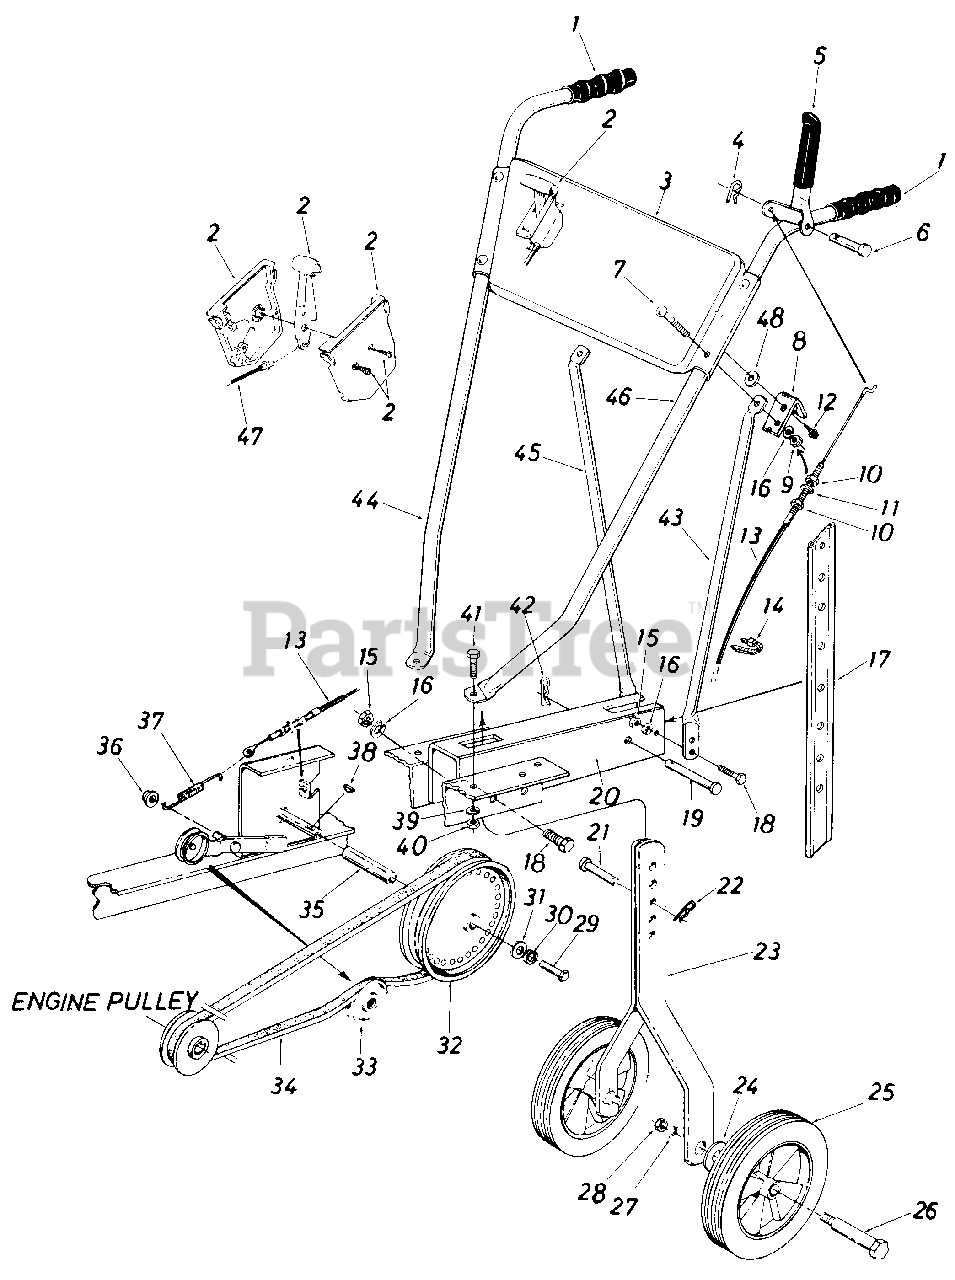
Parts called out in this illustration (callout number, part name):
2	Throttle Control Box
3	Handle Panel
4	Int. Cotter Pin
5	Clutch Grip Ass'y.
6	Clevis Pin
7	Carriage Bolt 5/16-18 x 1.75" Lg.*
8	Cable Support Brkt.
9	Hex Nut 5/16-18 Thd.*
10	Hex Jam Nut 5/16-24 Thd.
11	L-Wash. 5/16" I.D.*
12	Hex Wash Hd. Self-Tap Scr 1/4 20 x 50" Lg.
13	Clutch Control Cable
14	Cable Tie
15	Hex Nut 5/16-18 Thd.*
16	L-Wash. 5/16" I.D.*
17	Depth Bar
18	Hex Bolt 5/16-18 x .75" Lg.*
19	Clevis Pin 1/2" Dia. x 2.50" Lg .
20	Tailpiece Ass'y.
21	Clevis Pin 3/8" Dia. x 2.50" Lg .
22	Hairpin Cotter
23	Wheel Bracket Ass'y.
24	Belleville Wash. 1/2" I.D.
25	Wheel Ass'y. 9 x 1.75
26	Shoulder Bolt
27	L-Wash. 1/2" I.D.*
28	Hex Nut 1/2-20 Thd.*
29	Hex Bolt 1/4-28 x .75" Lg.
30	L-Wash. 1/4" I.D.*
31	Fl-Wash. .25" I.D. x .930" O.D.
32	Pulley 6.00" O.D.
33	Idler Pulley
34	V-Belt 1/2 " Pitch x 39" Lg.
35	Spacer
36	Cap Speed Nut
37	Extension Spring
38	Hi-Pro Key
39	L-Wash. 5/16" I.D.*
40	Hex Nut 5/16-18 Thd.*
41	Hex Bolt 5/16-18 x .75" Lg.*
42	Hairpin Cotter
43	Handle Support Bracket L.H.
44	Handle Bar R.H.
45	Handle Support Bracket R. H .
46	Handle Bar L.H.
47	Throttle Control Cable 35"
48	Fl-Wash. .281" I.D. x .50" O.D.
